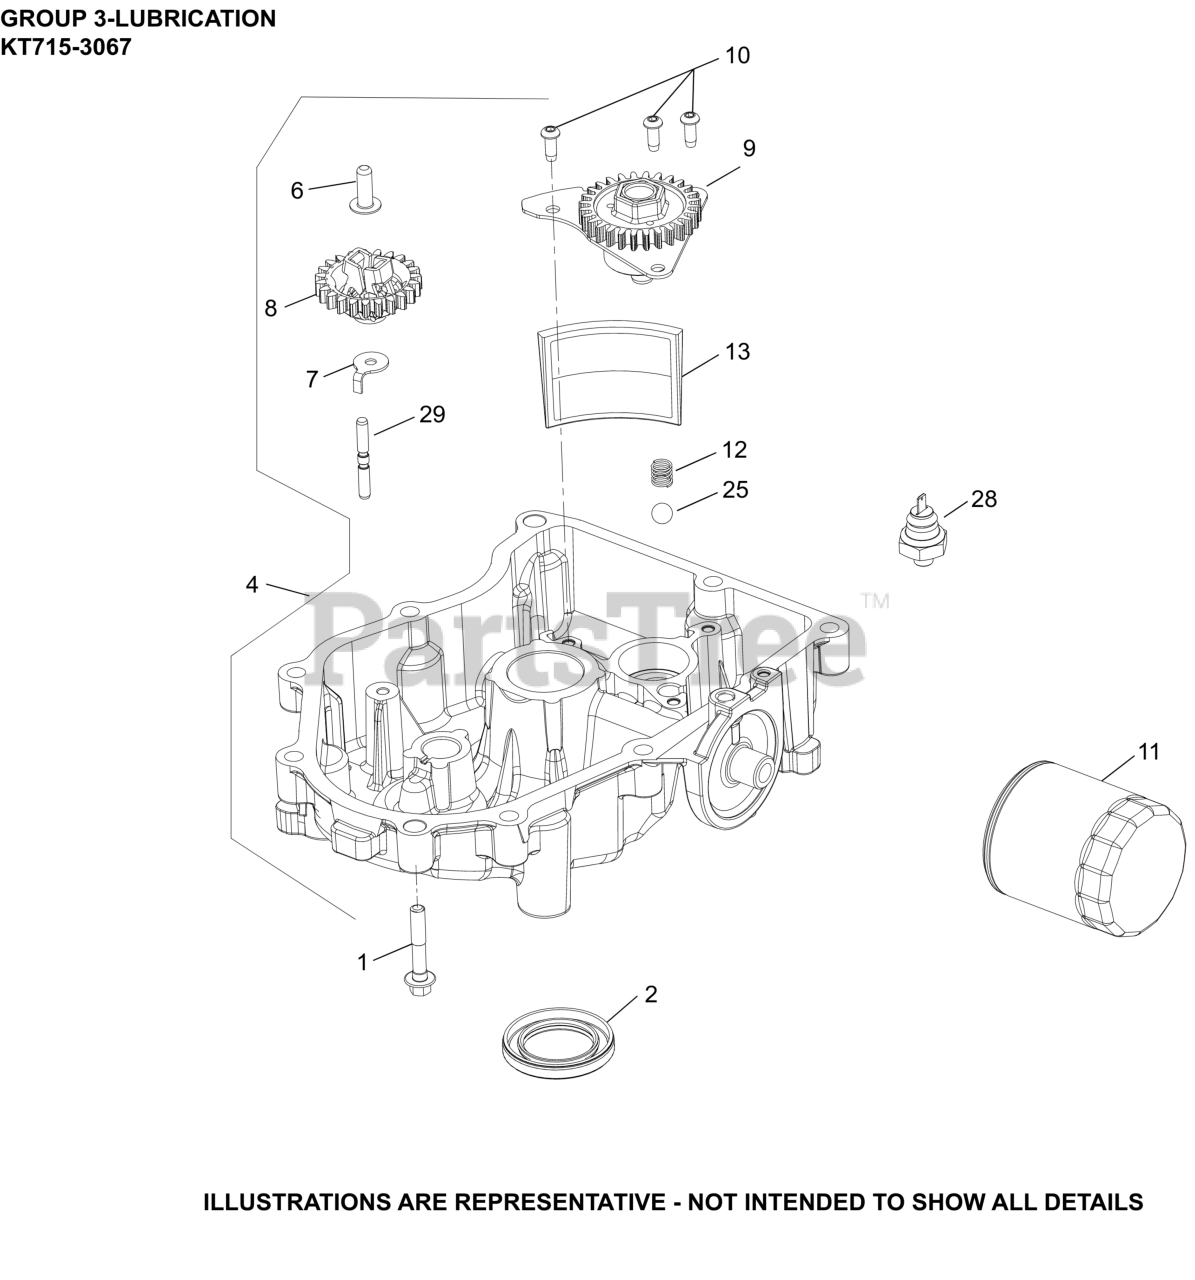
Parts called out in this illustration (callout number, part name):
1	SCREW, FLG M8X1.25X45
4	OIL PAN ASSEMBLY, (ROLLER BURNISHED)
6	PIN, GOVERNOR REGULATING
7	TAB, LOCKING
8	KIT, GOVERNOR GEAR
9	PUMP ASSEMBLY, OIL
10	SCREW, BUTTON HEAD
11	OIL FILTER
12	SPRING, COMPRESSION
13	SCREEN, OIL
25	PRESSURE RELIEF BALL
28	SWITCH, OIL PRESSURE(NC 3-6 PSI TO OPEN)
29	SHAFT, GOVERNOR GEAR
NI	PLUG, PIPE CTSK 3/8"
